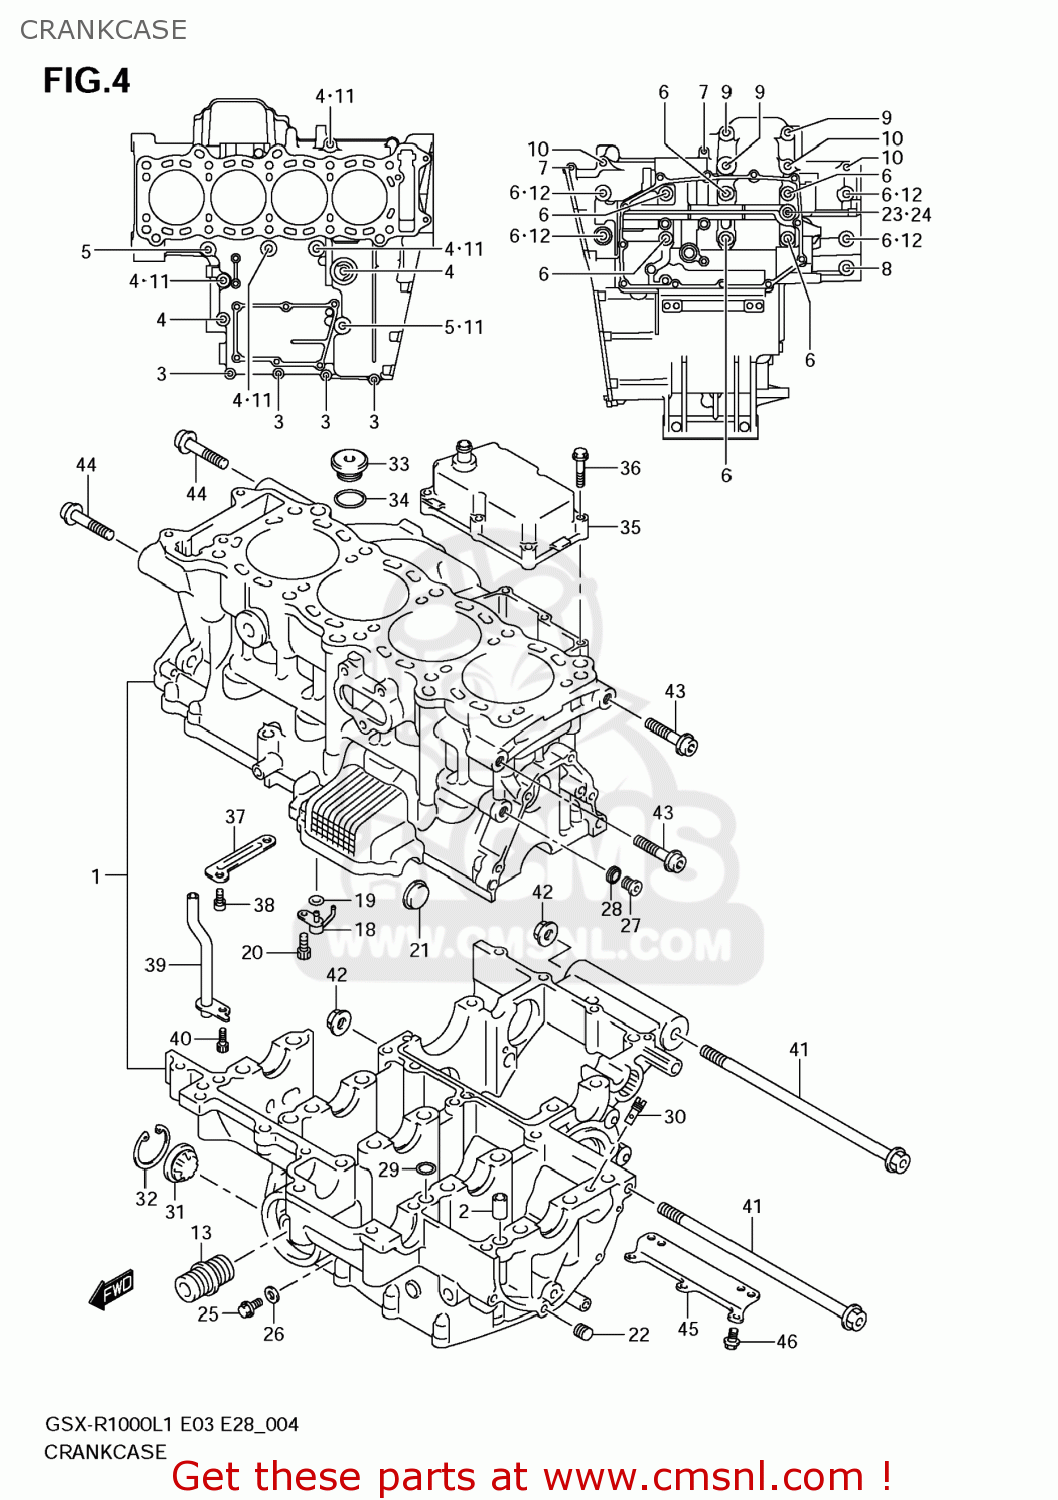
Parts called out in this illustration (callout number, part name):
1	CRANKCASE ASSY
2	PIN,CRANKCASE
3	BOLT
4	BOLT
5	BOLT
6	BOLT(9X95)
7	BOLT
8	BOLT
9	BOLT
10	BOLT
11	GASKET(8.2X14X1) (NAS)
12	GASKET(10.2X20X2).3 (NAS)
13	UNION,OIL STAND
14	O RING(D:3,ID:102)
15	BOLT(6X20)
16	BEARING,CRANK THRUST(GREEN)
17	BEARING,CRANK THRUST(RED)
18	JET,PISTON COOLING
19	O RING(D:1.2,ID:4)
20	BOLT(6X12)
21	PLUG
22	PLUG(1/8PT,H:5.5)
23	PLUG(L:12)
24	GASKET(12.1X16.2X3.7) (NAS)
25	BOLT
26	GASKET(6.2X13X1.2) (NAS)
27	PLUG(10X10)
28	GASKET(10X14X3.6) (NAS)
29	O RING(D:1.9,ID:7.8)
30	JET(140)
31	LENS,OIL LEVEL CHECK
32	CIRCLIP
33	PLUG(26X9)
34	O RING(D:3.1,ID:22.7)
35	COVER,BREATHER
36	BOLT
37	PLATE,BREATHER OIL RETURN
38	BOLT(6X12)
39	PIPE,BREATHER OIL RETURN
40	BOLT
41	BOLT(12X220)
42	NUT
43	BOLT(10X45)
44	BOLT(10X55)
45	PLATE,CRANKCASE LWR
46	BOLT(6X10)
